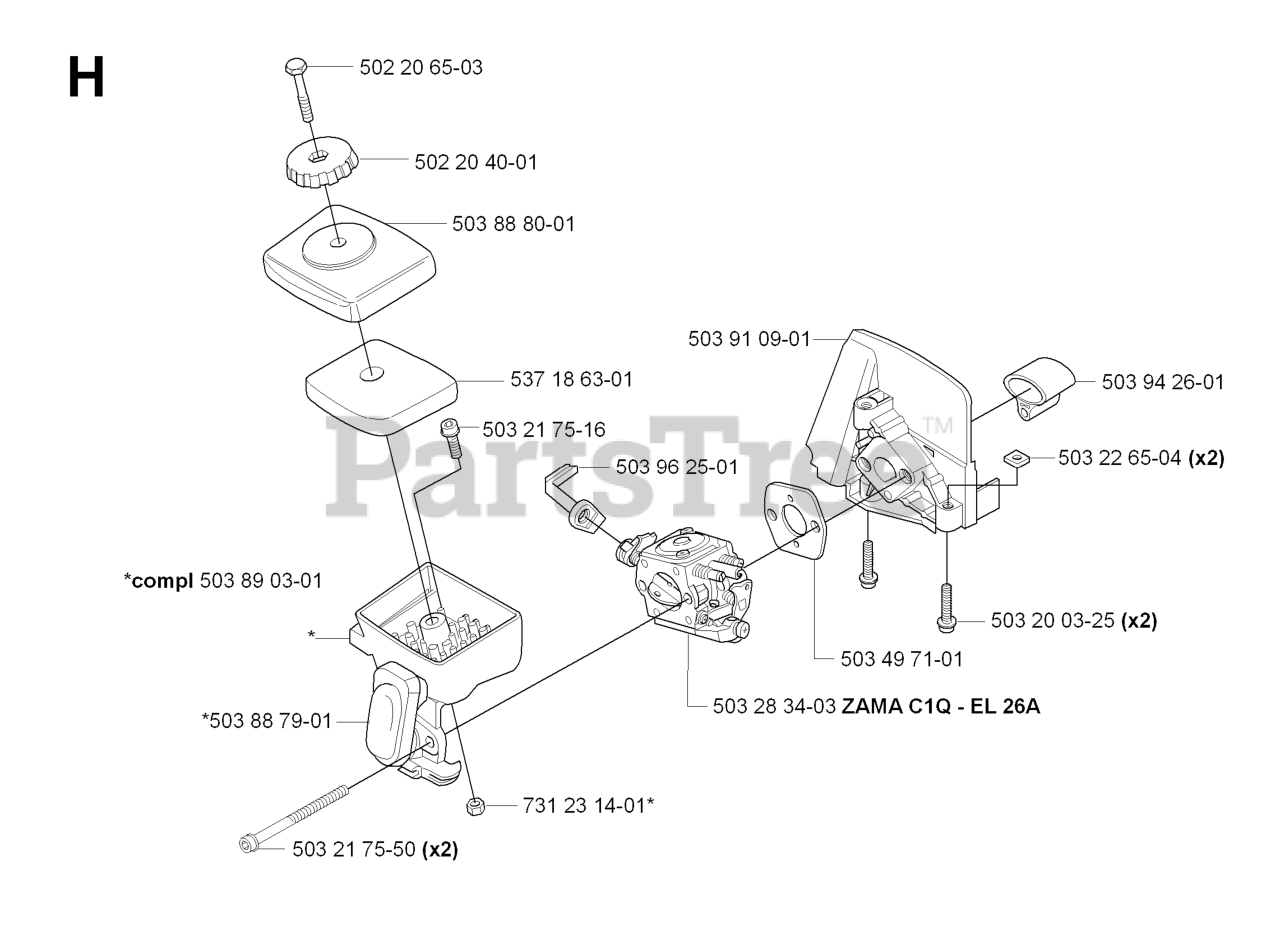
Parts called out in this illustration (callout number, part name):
1	BUMPER.ASM.TILLER.BLACK
2	LOCKNUT-FLANGE 5/16-18
3	WASHER
4	BOLT
5	BRACKET.REINFORCEMENT.RH.BLACK
6	BOLT, HEX 5/16-18X1-3/4
7	COUNTERWEIGHT.RH
10	BOLT
11	RETAINER M
12	RIVET
13	WHEEL.DRT.RH.13X5X6.SILVER.KEN
